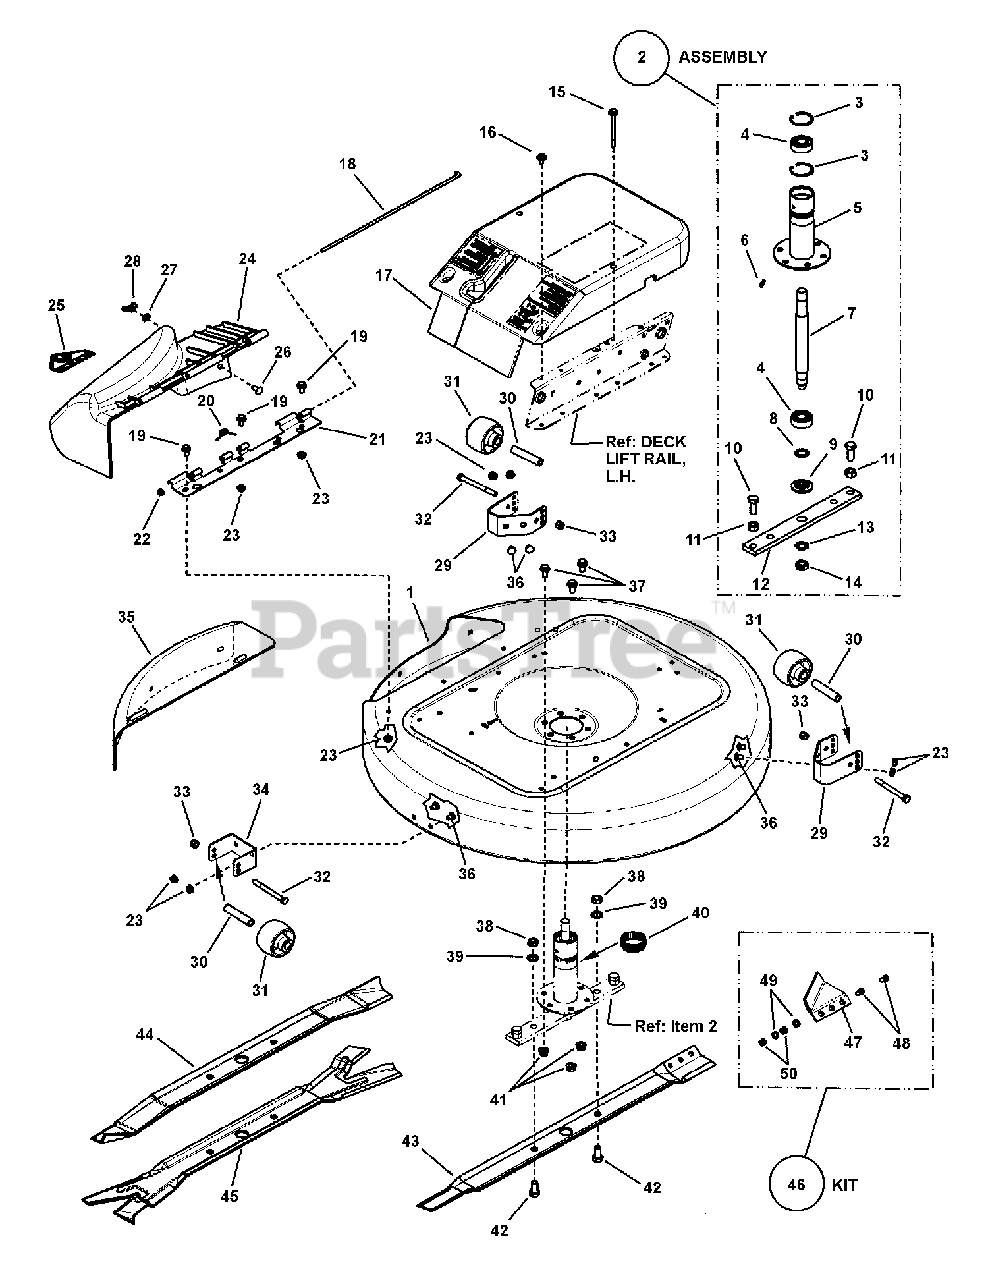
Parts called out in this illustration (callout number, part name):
1	DECK, 33" Replacement (painted deck w/decals)
2	ASSEMBLY, Spindle Housing (Incl. items 3 thru 14)
3	RING, 1.85" Internal Retaining
4	BEARING, Spindle
5	ASSEMBLY, Housing (Incl. grease fitting, 7010817)
6	LUBE FITTING, 3/16" Press-In
7	SPINDLE, Rider (10.327" overall length)
8	WASHER, .77 x 1.13 x .06 Flat
9	WASHER, Spindle
10	SCREW, 1/2-20 x 1-1/4" Hex Head Cap, GR 5
11	NUT, 1/2-20 Hex, GR 5 or B
12	HOLDER, Blade
13	SPACER, Blade Centering
14	NUT, 5/8-18 Hex Center Lock Jam
15	SCREW, 1/4-20 x 3-1/2" Hex Head w/Free Spinning Washer
16	SCREW, 1/4-20 x 5/8" Hex Head w/Free Spinning Washer
17	COVER, Spindle
18	PIN, Hinge
19	BOLT, 5/16-18 x 5/8" Hex Flange Lock, GR 5
20	SPRING, Hinge
21	HINGE, Deflector (Deck side)
22	PUSH NUT, 1/4"
23	NUT, 5/16-18 Hex Flange Lock, GR 5
24	DEFLECTOR, Discharge, 28" & 33"
25	DECAL, Danger, (Cut Finger) International Symbol
26	BOLT, 5/16-18 x 3/4" Short Neck Carriage, GR 5
27	WASHER, 5/16" Flat
28	NUT, 5/16-18 Wing
29	BRACKET, Gage Wheel (Rear)
30	SPACER
31	WHEEL, Gage
32	SCREW, 3/8-24 x 3-3/4" Hex Head Cap, GR 5
33	NUT, 3/8-24 Hex Nyloc
34	BRACKET, Gage Wheel (Front)
35	COVER, 33" Mulcher
36	BOLT, 5/16-18 x 1/2" Short Neck Carriage, GR 5
37	BOLT, 3/8-16 x 3/4" Hex Flange Lock
38	NUT, 1/2-20 Hex Jam
39	WASHER, 1/2" Internal Tooth Lock
40	RING, Tolerance
41	NUT, 3/8-16 Hex Flange Lock
42	SCREW, 1/2-20 x 1" Hex Head Cap, GR 5
43	BLADE, 33"
44	BLADE, 33" Mulcher
45	BLADE, Ninja, 33"
46	KIT, Air Lift, Hi-Vac (Includes items 47, 48, 49 & 50)
47	AIR LIFT, Hi-Vac (3 hole)
48	SCREW, 5/16-24 x 11/16" Oval Head Machine
49	WASHER, 5/16" Internal Tooth Lock
50	NUT, 5/16-24 Hex
